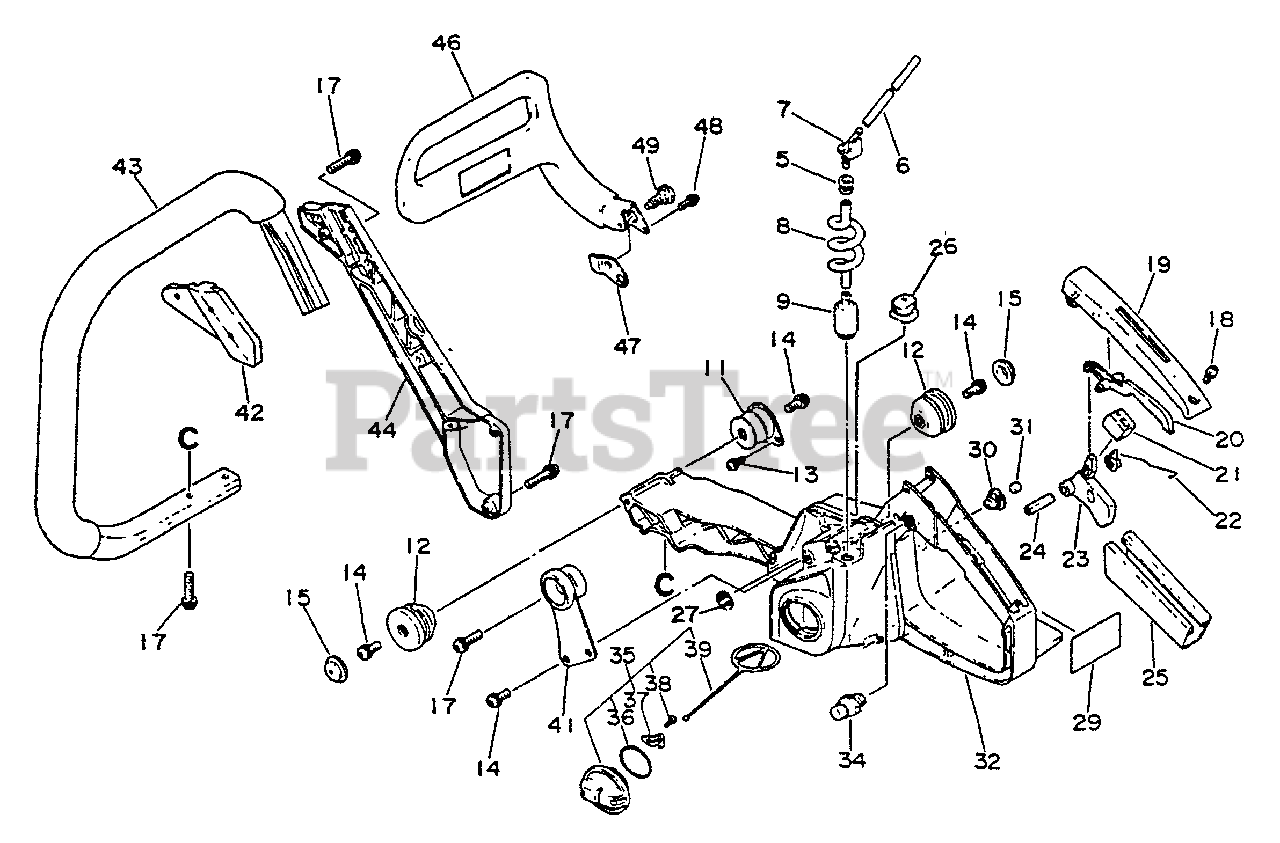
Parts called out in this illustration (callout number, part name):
5	GROMMET
6	PIPE - 3X6X120 -- BLACK
7	CONNECTOR, PIPE
8	PIPE - BLACK
9	FILTER, FUEL
13	SCREW - 4X10
14	SCREW - 5X14
15	CAP, CUSHION
17	SCREW - 5X20
18	SCREW - 4X14
19	GRIP, HANDLE - REAR
20	LOCKOUT, THROTTLE
21	CUSHION
22	SPRING, TRIGGER
23	TRIGGER, THROTTLE
24	PIN - SPRING -- 5X25
25	GRIP, HANDLE
29	LABEL - CAUTION
32	HANDLE - REAR
34	LATCH, THROTTLE
35	CAP ASSY
36	O-RING - 29
37	RETAINER
38	SCREW - 3X8
39	CONNECTOR, CAP
42	BRACKET, HANDLE - INNER
43	HANDLE - FRONT
44	BRACKET, HANDLE - OUTER
48	SCREW - 4X10
